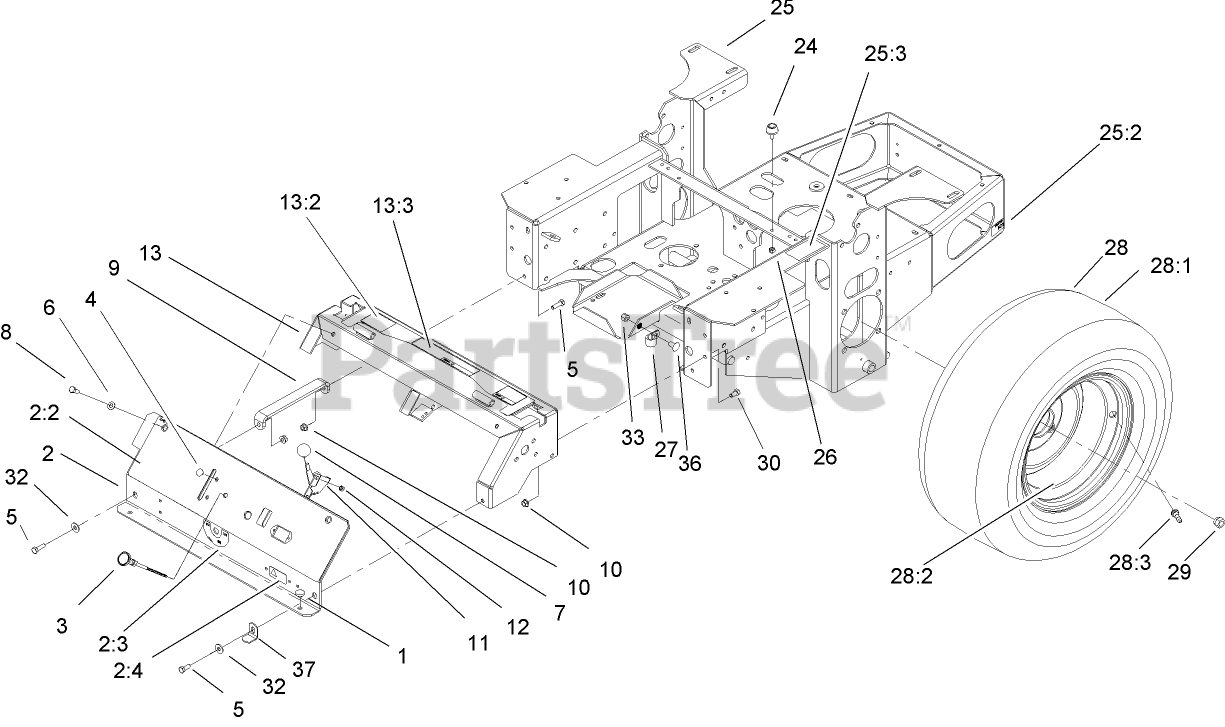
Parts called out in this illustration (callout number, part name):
1	BUMPER
2	Console ASM
2:2	DECAL-PANEL, CONTROL
2:3	DECAL-VALVE, FUEL
2:4	DECAL-PROTECTION, EAR
3	CONTROL-CHOKE
4	BOLT-CARR
5	SCREW-HH
6	WASHER-PLAIN
7	KNOB-BALL
8	SCREW-HH
9	BRACKET
10	NUT-HF
11	THROTTLE CABLE ASM
12	NUT-LOCK, NI
13	CONSOLE
13:2	DECAL-CONTROL, MOTION
13:3	DECAL-BATTERY
24	BUMPER
25	MAIN FRAME ASM
25:2	DECAL-WARNING
25:3	Decal-Release, Drive
26	NUT-LOCK, NI
27	CLIP-LOOM
28	WHEEL AND TIRE ASM
28:1	TIRE
28:3	STEM-VALVE
29	NUT-LUG
30	SCREW-HH
32	WASHER-FLAT
33	NUT-LOCK, NI
36	SCREW-CARR
37	STOP-COVER
